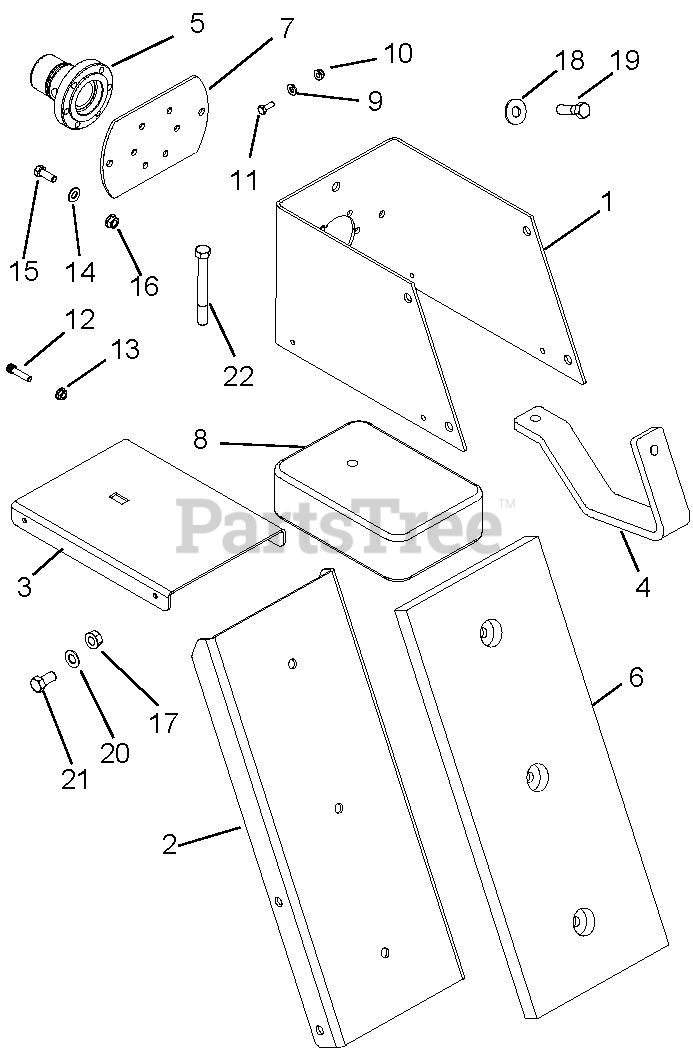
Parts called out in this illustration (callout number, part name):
1	FRAME, RAPID GRAVELY PUSHER
2	BUMPER, RAPID GRAVELY PUSHER
3	TRAY, RAPID GRAVELY PUSHER
4	SKID SHOE, CAR PUSHER
5	FLANGE, ADAPTER
6	RUBBER BUMPER, CAR PUSHER
7	PLATE, PUSHER MOUNT BACKUP
8	WEIGHT, RAPID PUSHER
9	@WSHR-FL-STL.281X.62X.065 YWZC
10	@NUT-LK-NYL-FLG .25-20 YWZC
11	@BLT-HEX .25-20X.75 GR5 YWZC
12	SHCS .312-18 X 1.25 GR8 YWZC
13	@NUT-LK-TOP-FLG .31-18 YWZC
14	SHIM-BALL-BRG 1.50X2.125X.015
15	@BLT-HEX .38-16X1.00 GR5 YWZC
16	@NUT-LK-TOP-FLG .38-16 YWZC
17	@NUT-LK-TOP-FLG .50-13 YWZC
18	@WSHR-FL-STL.563X1.38X.109YWZC
19	@BLT-HEX .50-13X1.75 GR5 YWZC
20	WSHR-FL-STL.531X1.00X.063 YWZC
21	@BLT-HEX .50-13X1.00 GR5 YWZC
22	@BLT-HEX .50-13X4.50 GR5 YWZC
